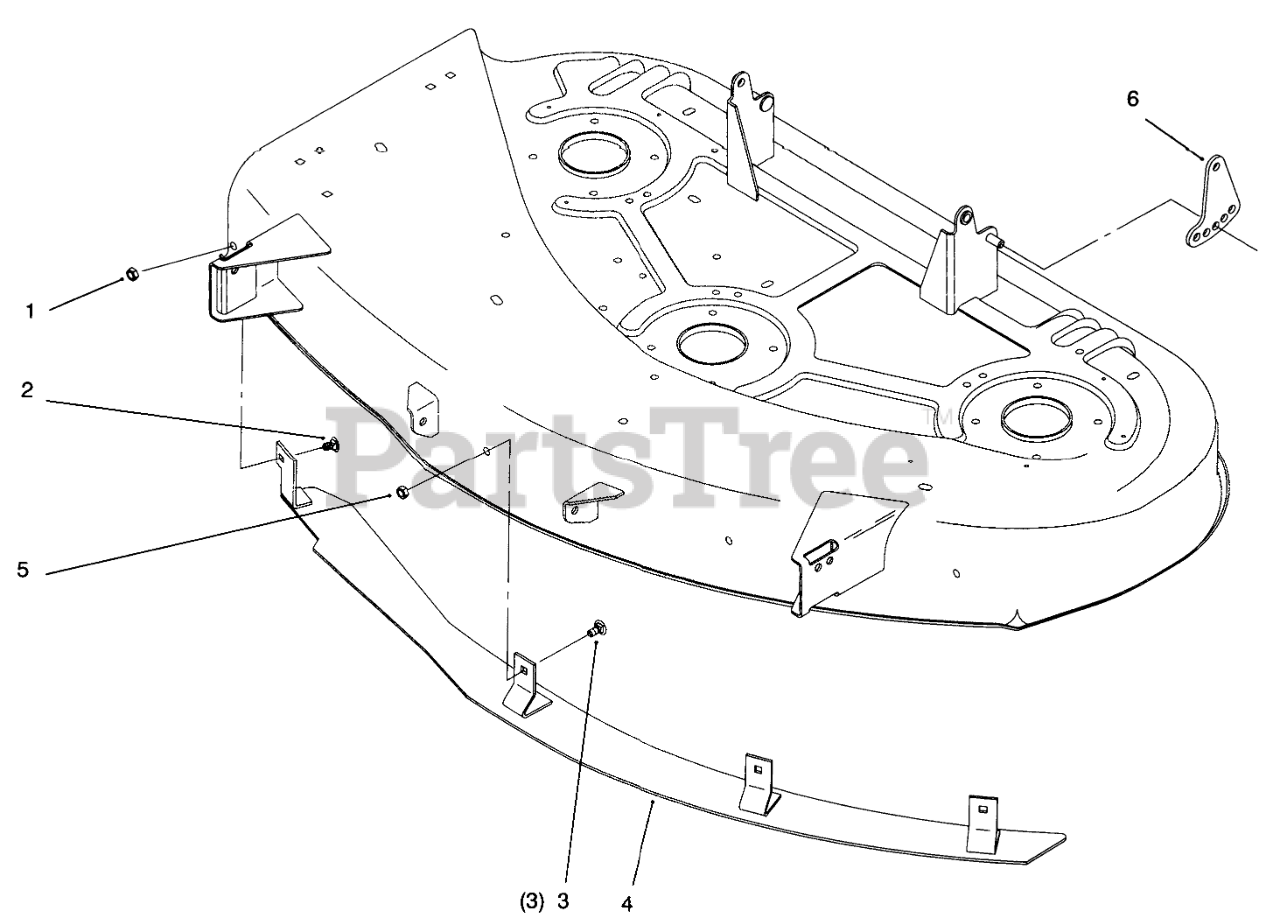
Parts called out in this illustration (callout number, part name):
1	NUT-LOCK, NI
2	SCREW-CARR
3	SCREW-CARR
4	BAFFLE WA BLACK (NS)
5	NUT-LOCK, NI
6	LINK - HOC ADJUSTING
